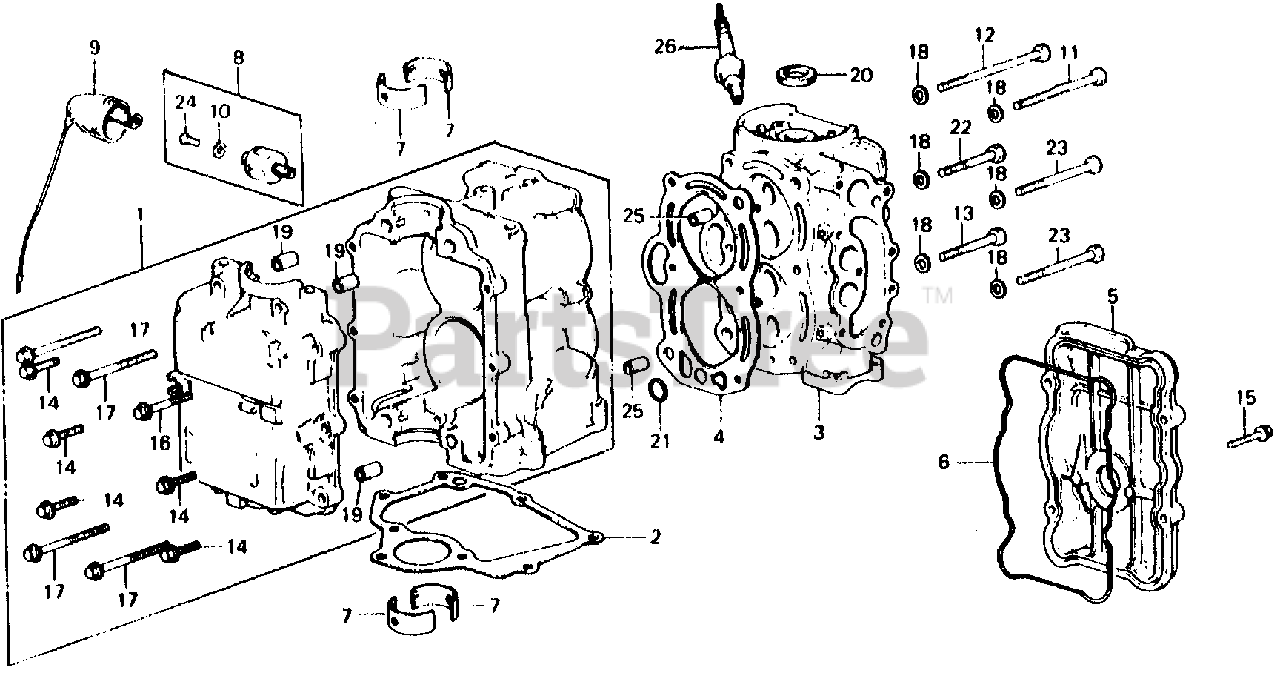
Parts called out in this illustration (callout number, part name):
1	CYLINDER ASSY. (NOT AVAILABLE)
2	GASKET, OIL PAN
3	CYLINDER HEAD (NOT AVAILABLE)
4	GASKET, CYLINDER HEAD
5	COVER, CYLINDER HEAD *NH8* (DARK GRAY)
6	GASKET, HEAD COVER
7	BEARING, CRANKSHAFT
8	SWITCH, OIL PRESSURE
9	WIRE, OIL PRESSURE SWITCH
10	WASHER (4MM)
11	BOLT, HEAD (8X70)
12	BOLT, HEAD (8X94)
13	BOLT, HEX. (8X55)
14	BOLT, FLANGE (6X25)
15	BOLT, FLANGE (6X28)
16	BOLT, FLANGE (6X35)
17	BOLT, FLANGE (8X45)
18	WASHER, HEAD (8MM)
19	PIN, DOWEL (10X12)
20	OIL SEAL (16X28X6)
21	O-RING (10.8X2.4) (ARAI)
22	BOLT, HEX. (8X50) (NOT AVAILABLE)
23	BOLT, HEX. (8X65) (NOT AVAILABLE)
24	SCREW, PAN (4X6)
25	PIN, DOWEL (10X16)
26	SPARK PLUG (DR-4HS) (NGK)
26	SPARK PLUG (DR-5HS) (NGK)
26	SPARK PLUG (X16FSR-U) (DENSO)
